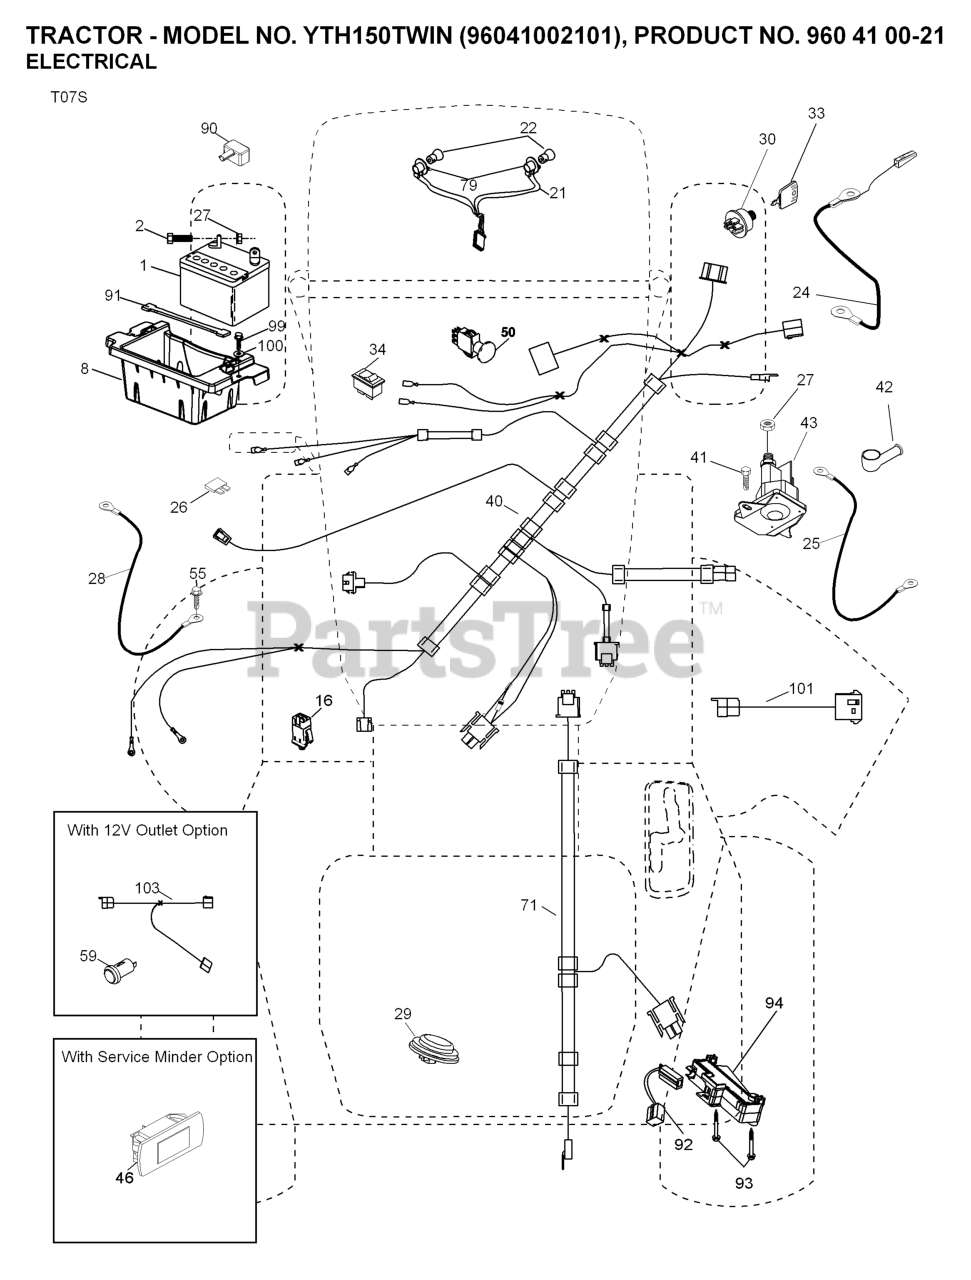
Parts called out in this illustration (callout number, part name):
1	Battery 12 Volt 25 Amp
2	BOLT.HEX.1/4.X.3/4.DICHROMATE
8	BOX.BATTERY.MOUNT.FRONT.LT
16	SWITCH INTERLOOK PUSH-IN
21	HARNESS ASSY LIGHT
24	CABLE.BATT.POS.WIRE.TG.DA SOL
25	CABLE.STARTER.6G.BL/RED.17.5
26	FUSE 20AMP
27	NUT
28	CABLE GROUND 6 GA 21" 90T BLK
29	SWITCH.SEAT.DELTA.OPC.
30	SWITCH.IGN.DELTA.W.LGH.ROS
33	KEY.CHAIN.BLISTER.PACK.GEN.INT
40	HARNESS-CHASSIS SUB
41	SCREW
42	TERMINAL COVER
43	SOLENOID.W/BRASS.PLUNGER
50	RP.PTO.SWITCH.8 TERMINAL.BLACK
55	SCREW 5/16"
71	HARNESS.IGN.DASH.HUQ/P
79	BULB HOLDER ASM.
90	COVER.TERMINAL.BATTERY
91	STRAP.BATTERY.MOUNT.FRONT(2 2)
92	HARNESS.PIGTAIL.CONSLE
93	SCREW.PLASTITE
94	MODULE.REVERSE.ROS
99	SCREW HEXWSHR 1/4-20X3/4
101	PIGTAIL.MATNLK.NEW.HAR
